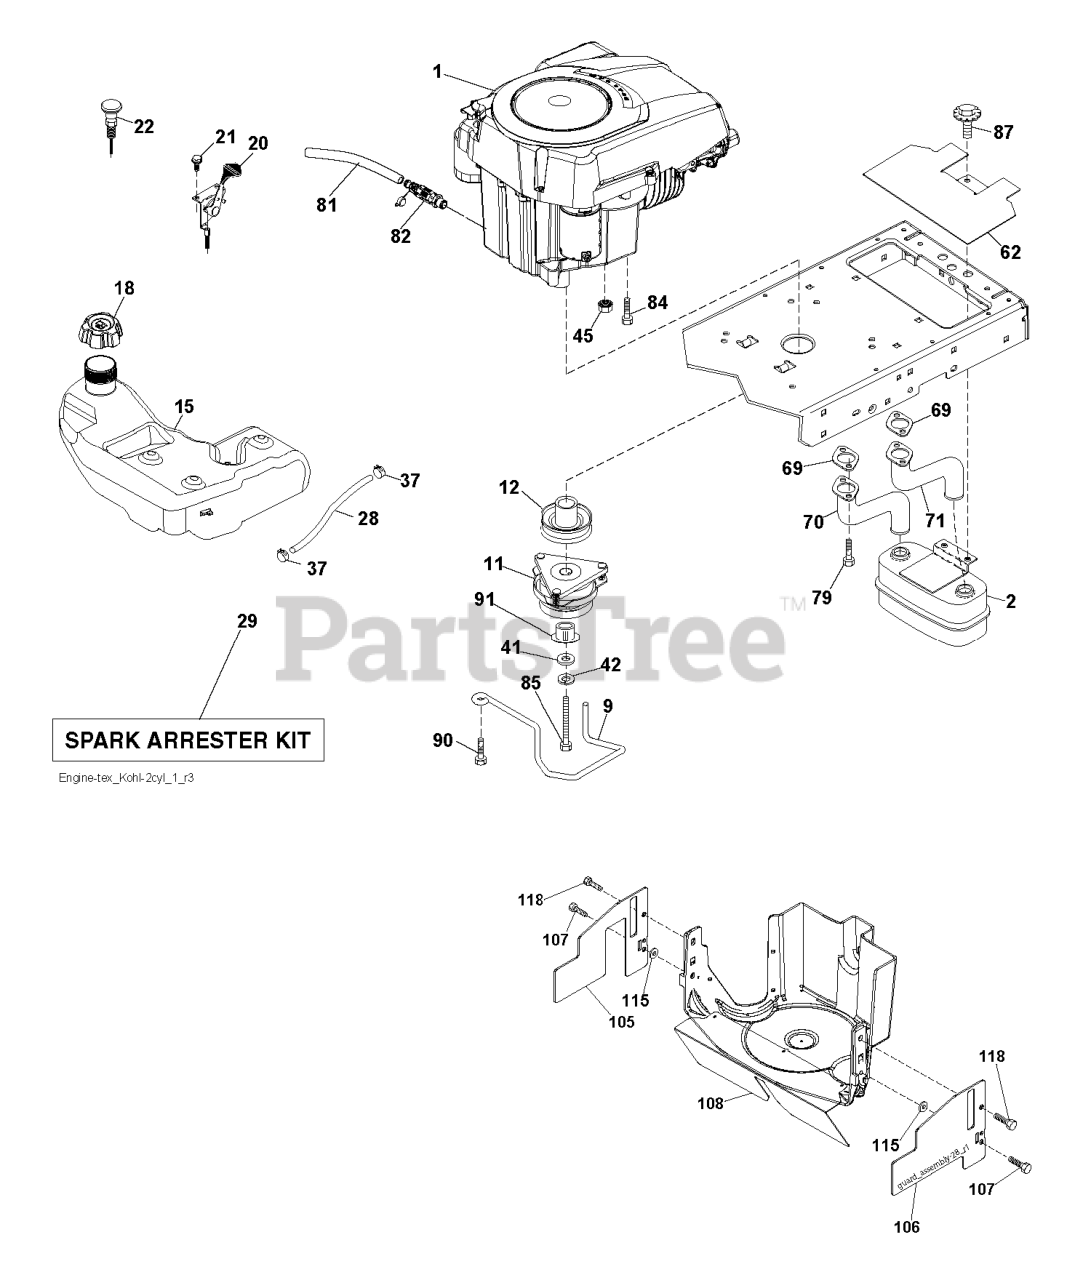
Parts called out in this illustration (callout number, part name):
2	MUFFLER.TWIN.CYL.LOW.TONE
9	KEEPER.BELT.ENGINE.4.2
11	CLUTCH.ELECTRIC.LT.48"*
12	PULLEY.ENGINE.TUFFTORQ
15	TANK.FUEL.4GAL
18	RP CAP FUEL
20	THROTTLE CONTROL
21	SCREW.#10 X 0.750.BOS
22	CONTROL.CHOKE.ERGO.PUSH-IN.BLA
28	REPL BY 532 00 85-43
29	KIT.SPARK ARRESTOR 794945 B&S
37	HOSE CLAMP
42	LOCKWASHER
45	NUT
62	RP SHIELD HEAT MUFFLER
69	GASKET.EXHAUST.KOHL.CV18-CV26
70	RP.PIPE-EXHAUST LH
71	RP.PIPE-EXHAUST RH
79	SCREW.SOCKET HD.5/16-1
81	TUBE, DRAIN OIL ASM.
82	VALUE.OIL.DRAIN
84	SCREW 3/8-16X1
85	BOLT HEX 7/16-20X4-1/4"
87	BOLT.5/16-18UNCX3/4 W/SEMS.BLK
90	SCREW 3/8-16X1
91	BUSHING.1.375OD
105	SHIELD.SIDE.RH.3842"TEX FRENCH
106	SHIELD.SIDE.RH.46"FRENCH.TEX
107	SCREW.1/4-20X5/8
108	COVER
115	PALNUT 1/4
118	SCREW, 5/16-18 X 1/2
